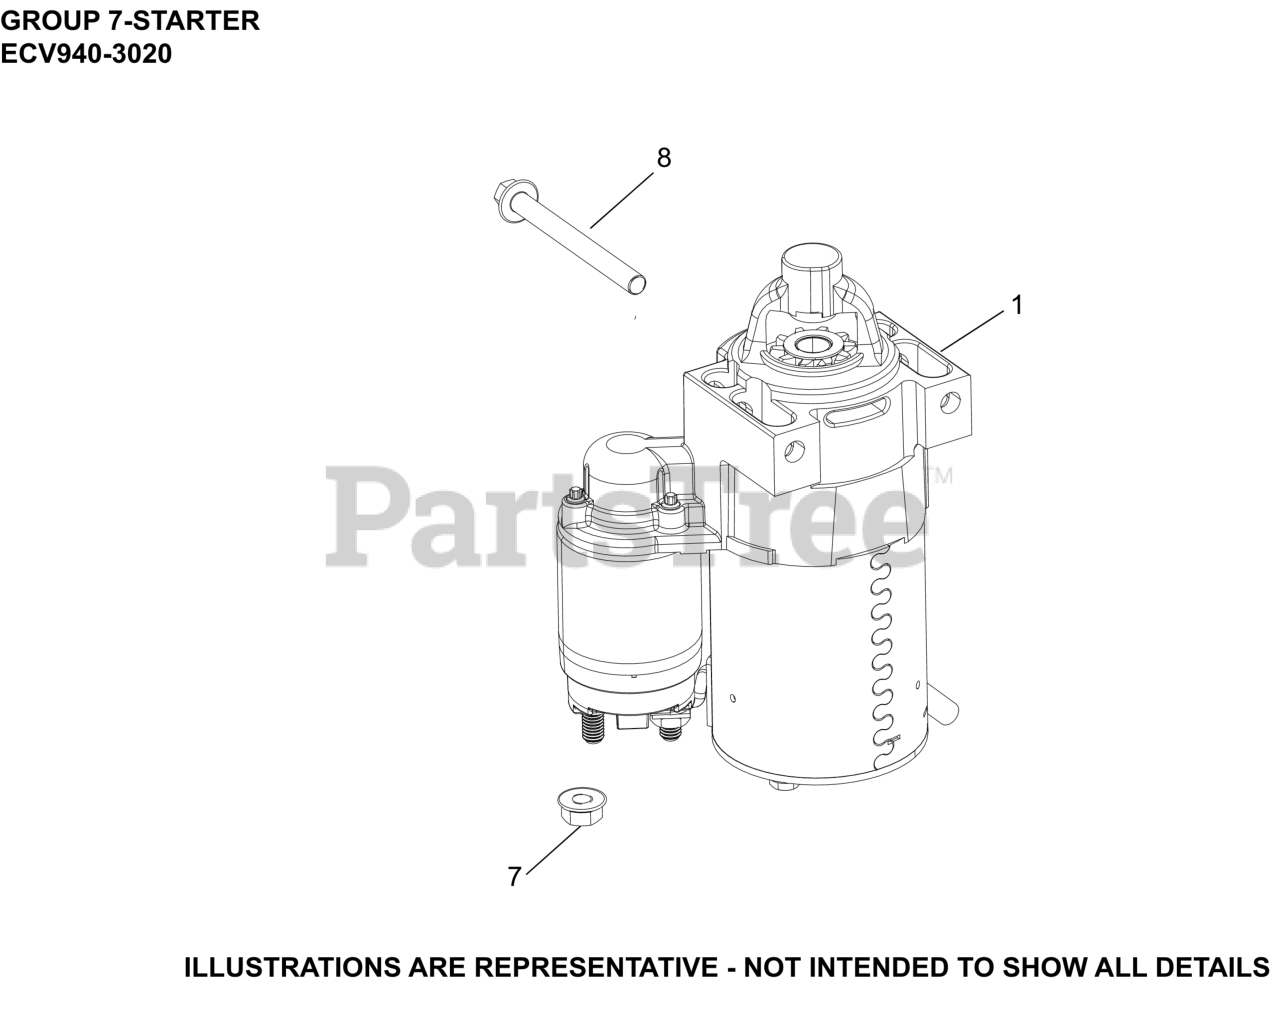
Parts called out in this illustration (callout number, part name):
1	STARTER, SOLENOID SHIFT (25 098 09-S)
7	NUT, FLG M8X1.25
8	SCREW, FLG M8X1.25X80
